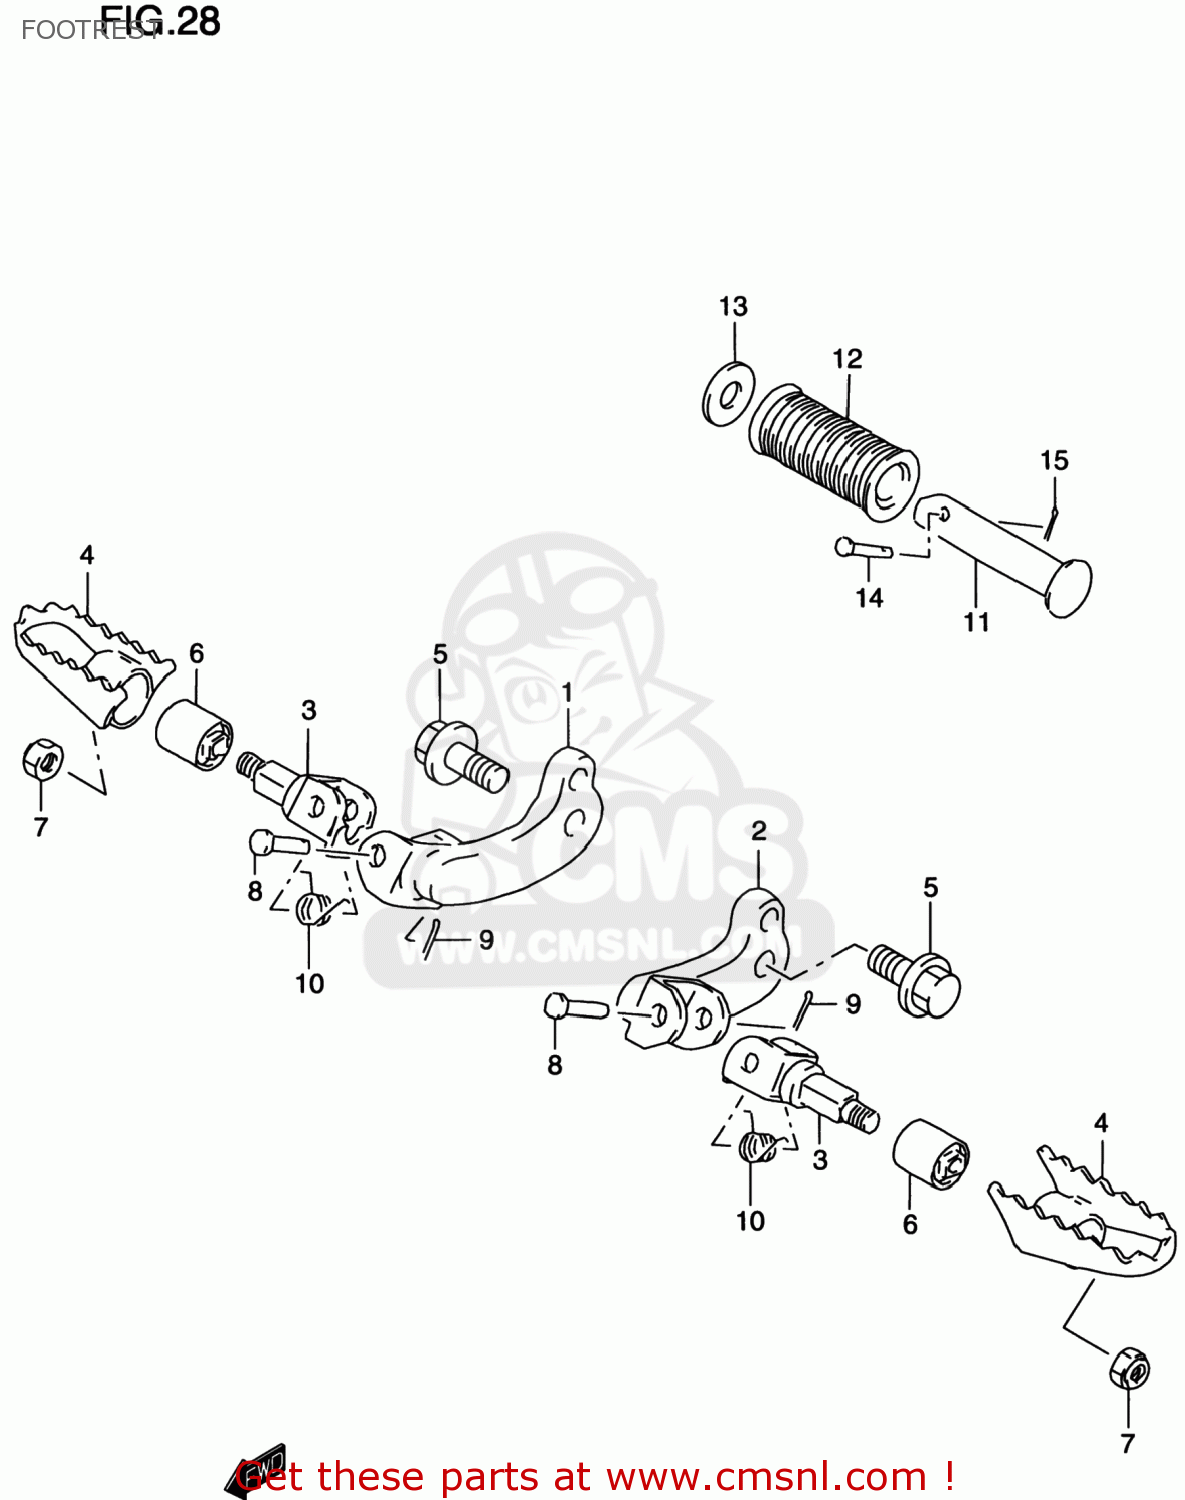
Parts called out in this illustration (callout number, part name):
1	BAR,FR FOOTREST,R
2	BAR,FR FOOTREST,L
3	BRACKET,FR FOOTREST
4	FOOTREST,FR
5	BOLT(12X25)
6	BUSH
7	NUT
8	PIN
9	PIN
10	SPRING
11	BAR,FOOTREST RUBBER
12	RUBBER,PILLION FOOTREST
13	WASHER(19.5X32X2)
14	PIN
15	PIN
